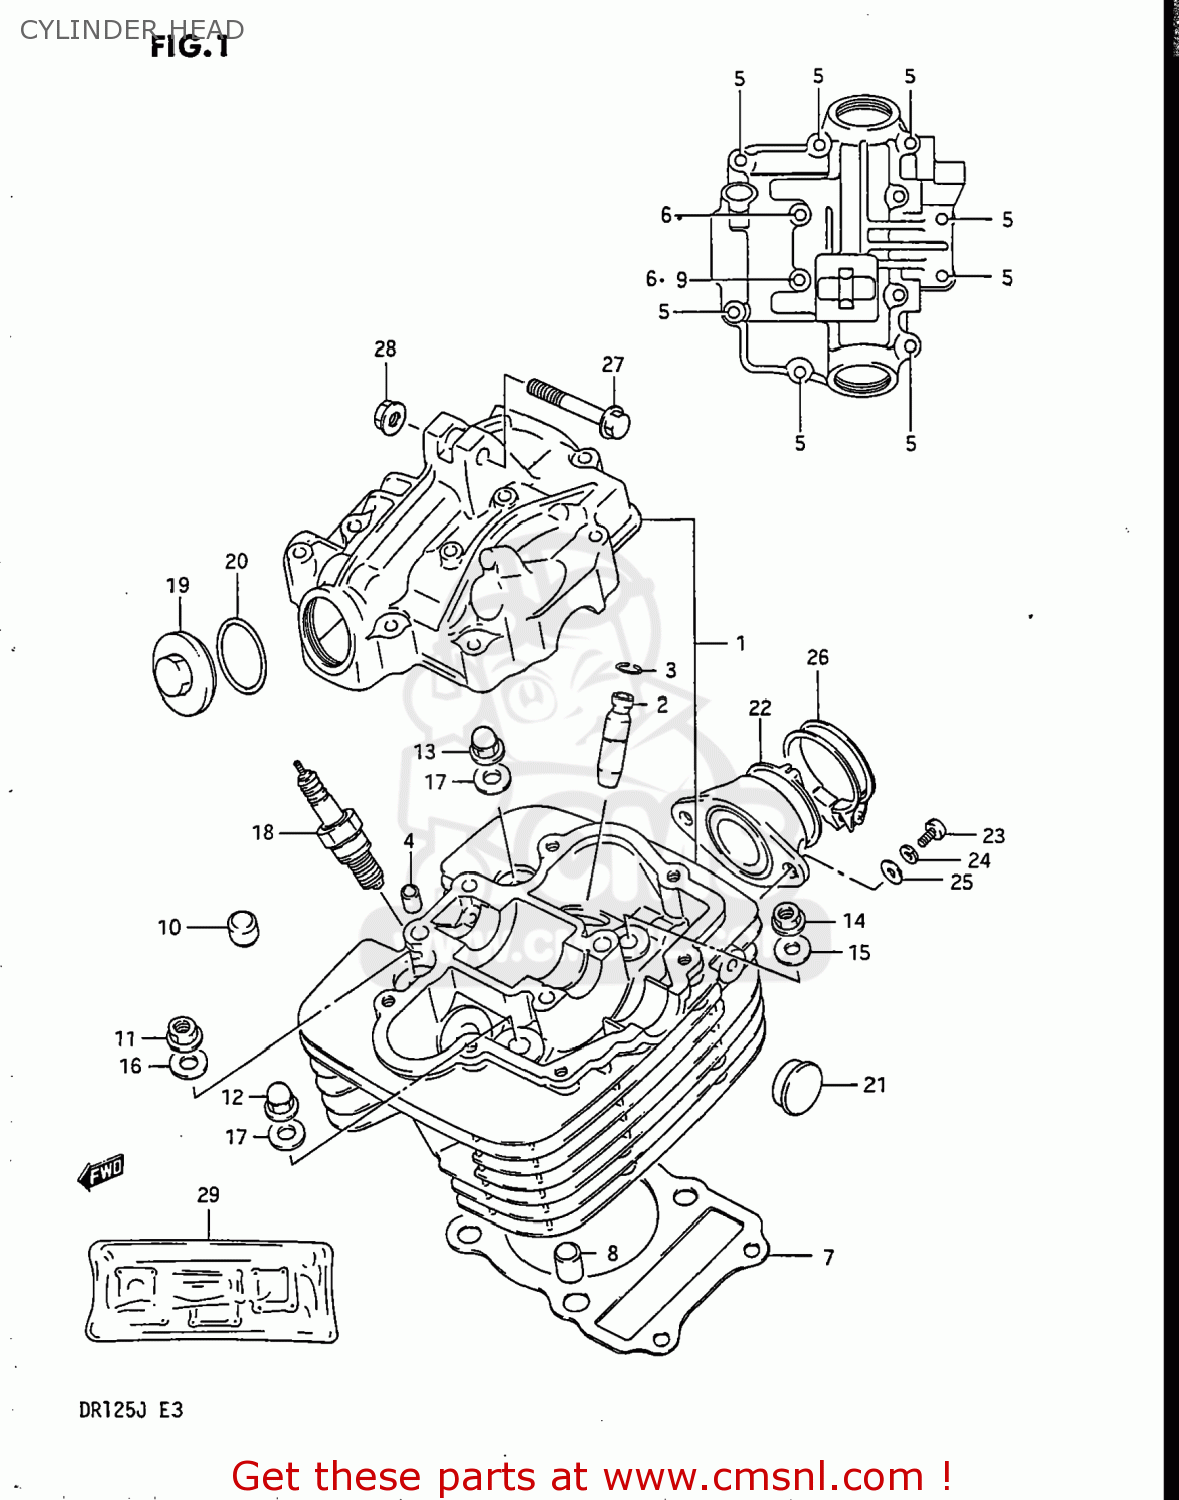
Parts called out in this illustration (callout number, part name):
1	HEAD ASSY,CYLINDER
2	GUIDE,VALVE
3	RING,SNAP
4	PIN(6.2X8X11)
5	BOLT 6X35
6	BOLT ,6X60
7	GASKET,CYLINDER HEAD (NAS)
8	PIN
9	WASHER
10	PAD,CYLINDER HEAD
11	NUT
12	NUT (8MM)
13	NUT 8MM
14	NUT
15	WASHER (8.5X19X2.3)
16	WASHER(8.5X19X2.3)
17	GASKET (NAS)
18	SPARK PLUG D8EA
19	CAP,INSPECTION
20	O RING(D:3,ID:29.5)
21	PLUG(OD:22.5)
22	PIPE,INTAKE
23	SCREW
24	WASHER,LOCK
25	WASHER
26	CLAMP
27	BOLT 8X50
28	NUT
29	GASKET SET (MCA)
